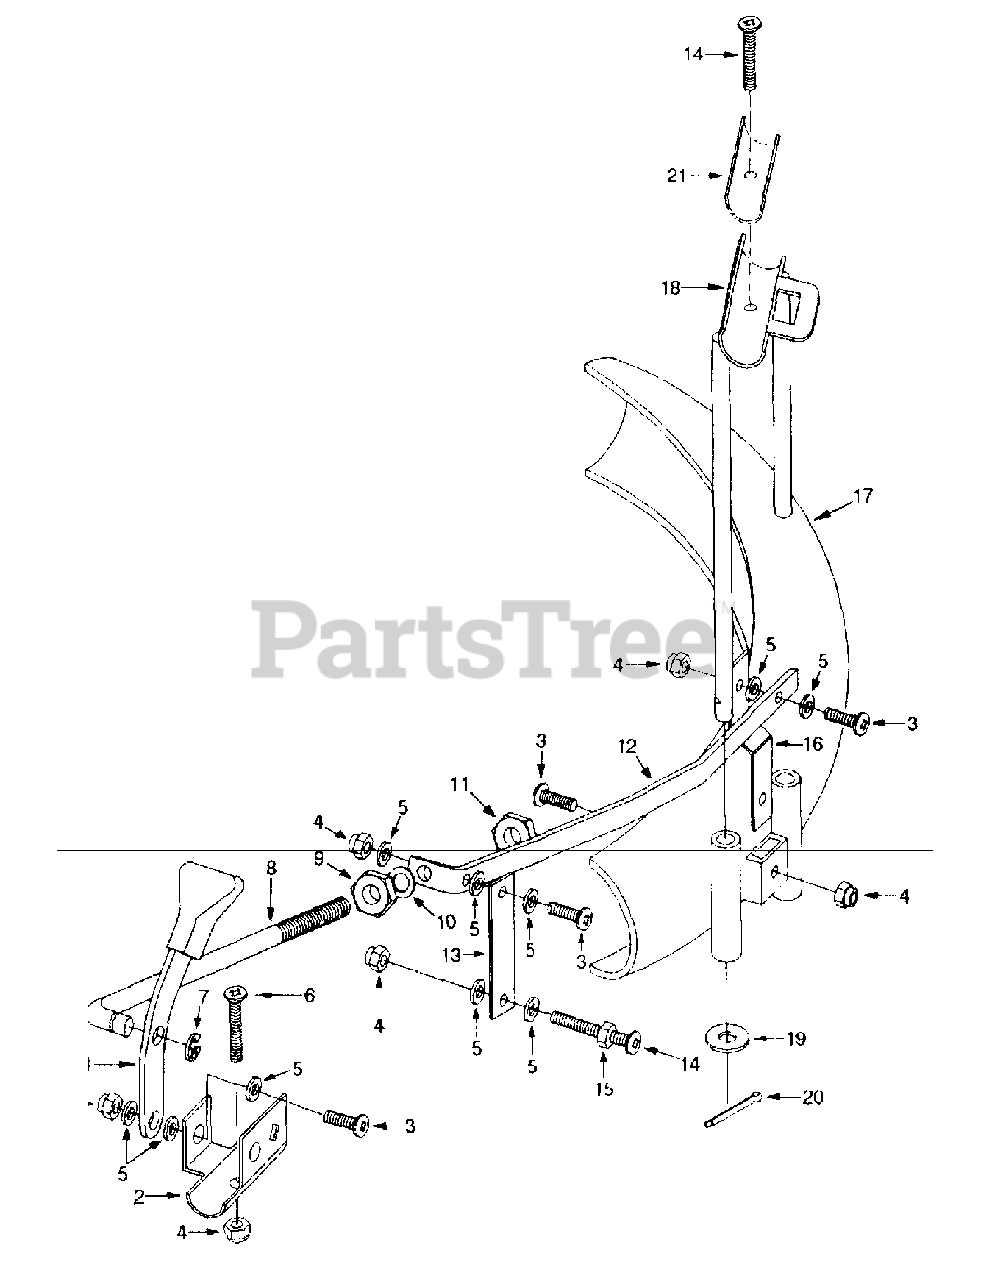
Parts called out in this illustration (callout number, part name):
1	Operating Lever and Rubber Handle
2	Bracket, Dual Lever
3	Machine Screw, 1/4-20 x 7/8 Pan Hd.
4	Hex Nut, 1/4-20 Nylock
5	Flat Washer, 1/4 Nylon
6	Mach. Screw, 1/4-20 x 1-1/2 Pan Hd.
7	Retainer, "C" Clip
8	Threaded Rod, Deflector
9	Hex Nut. 5/16-18
10	Lock Washer. 5/16
11	Hex Nut, 5/16-18 Nylock
12	Deflector Arm
13	Flat Plate, Deflector
14	Machine Screw, 1/4-20 x 2 Pan Hd.
15	Hex Nut.1/4-20
16	Offset Bracket
17	Deflector Tube
18	Deflector Bracket
19	Flat Washer, 3/8
20	Cotter Pin, 1/8 x 1
21	Rubber Pad
